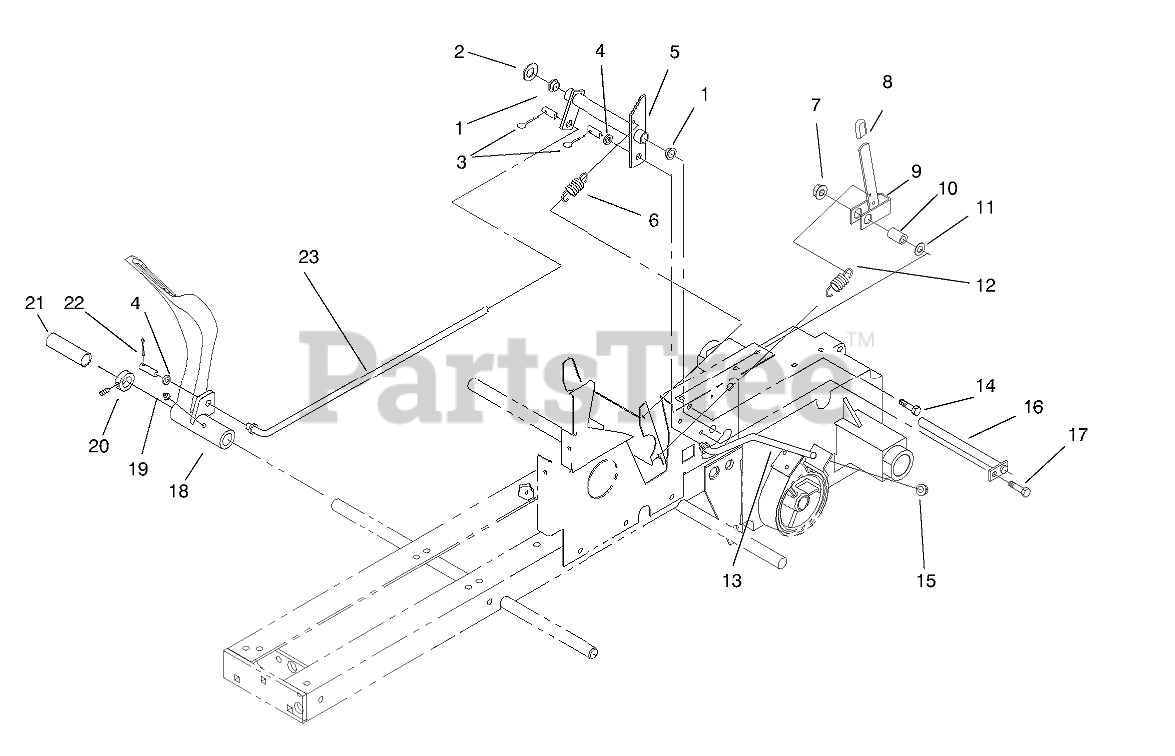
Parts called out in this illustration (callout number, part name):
1	BUSHING-FLANGED
2	WASHER-FLAT
3	PIN-HAIR
4	WASHER-NYLON
5	BELCRANK ASM
6	SPRING-EXTENSION
7	NUT-HF
8	GRIP
9	BRAKE LEVER ASM
10	SPACER
11	WASHER-FLAT
12	SPRING-BRAKE
13	ROD-REAR BRAKE
14	SCREW-HH
15	NUT-LOCK, NI
16	ROD ASM
17	Bolt
18	PEDAL-BRAKE, GEAR
19	FITTING-GREASE
20	COLLAR
21	SLEEVE-PROTECTIVE
22	PIN-COTTER
23	ROD-BRAKE
